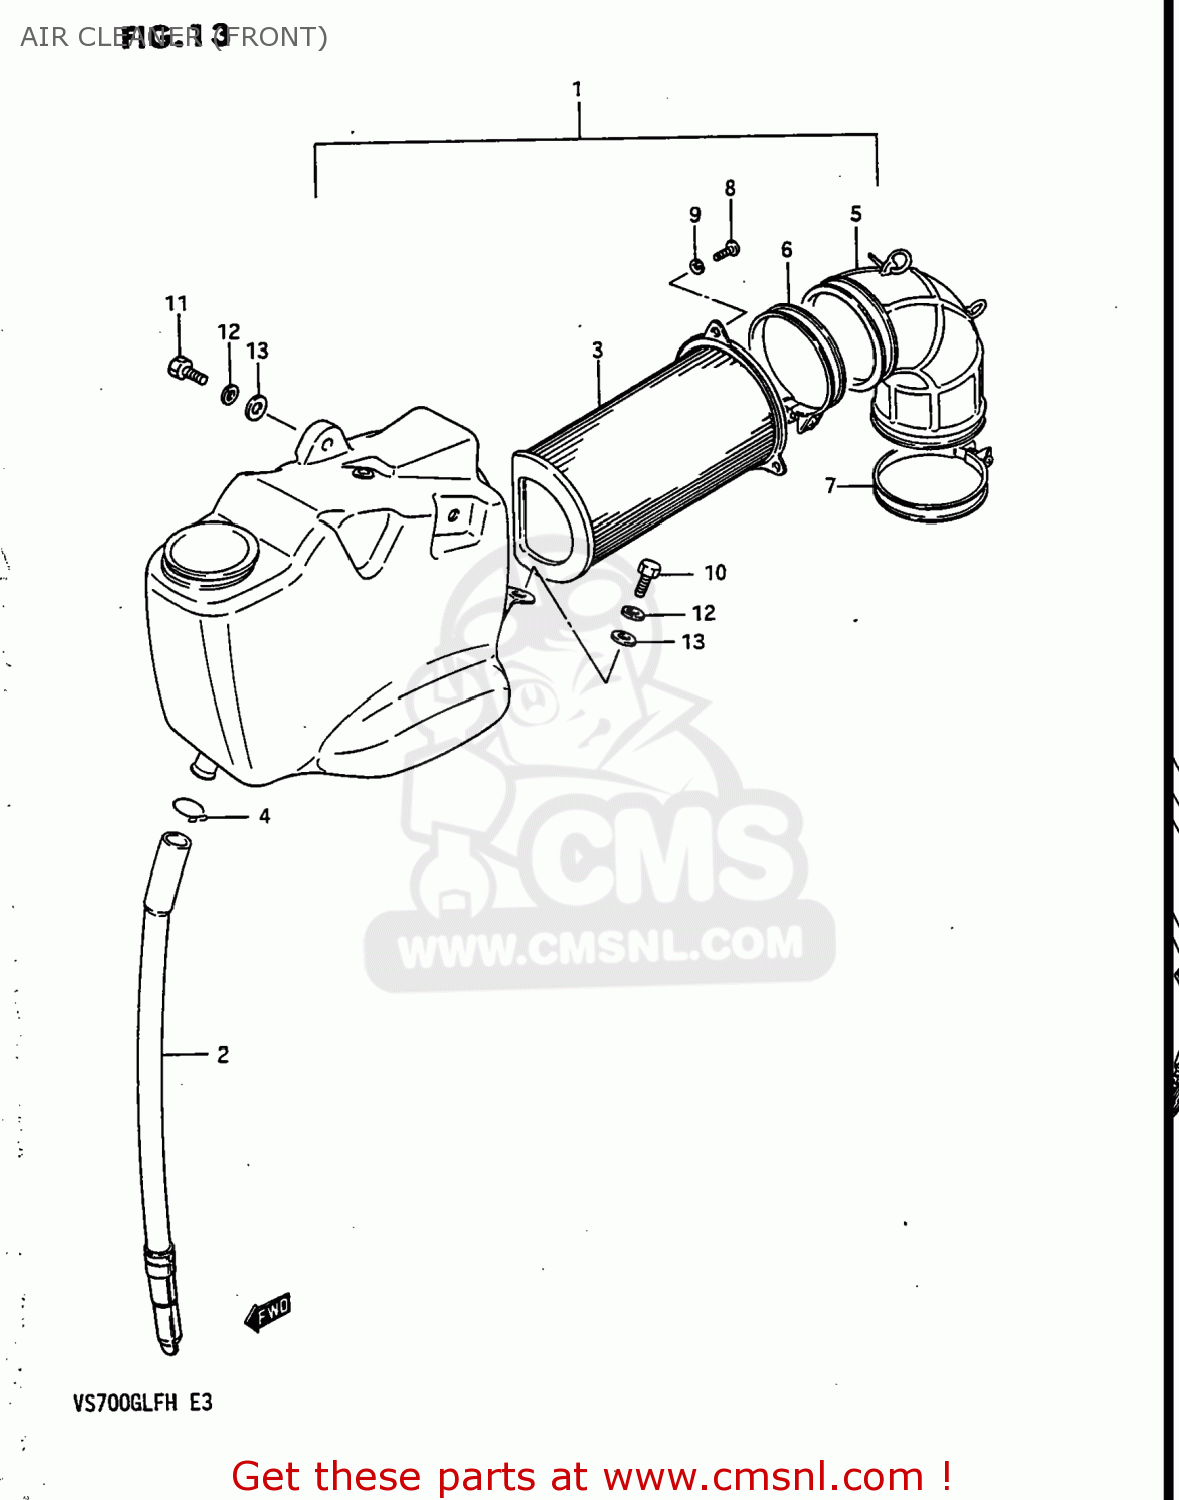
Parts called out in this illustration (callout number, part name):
1	CLEANER ASSEMBLY,AIR
2	DRAIN TUBE
3	FILTER,AIR CLEANER
4	CLIP
5	TUBE,AIR CLEANER OUTLET
6	CLAMP
7	CLAMP
8	SCREW
9	LOCK WASHER
10	BOLT, UPPER
11	BOLT
12	WASHER,LOCK
13	WASHER
